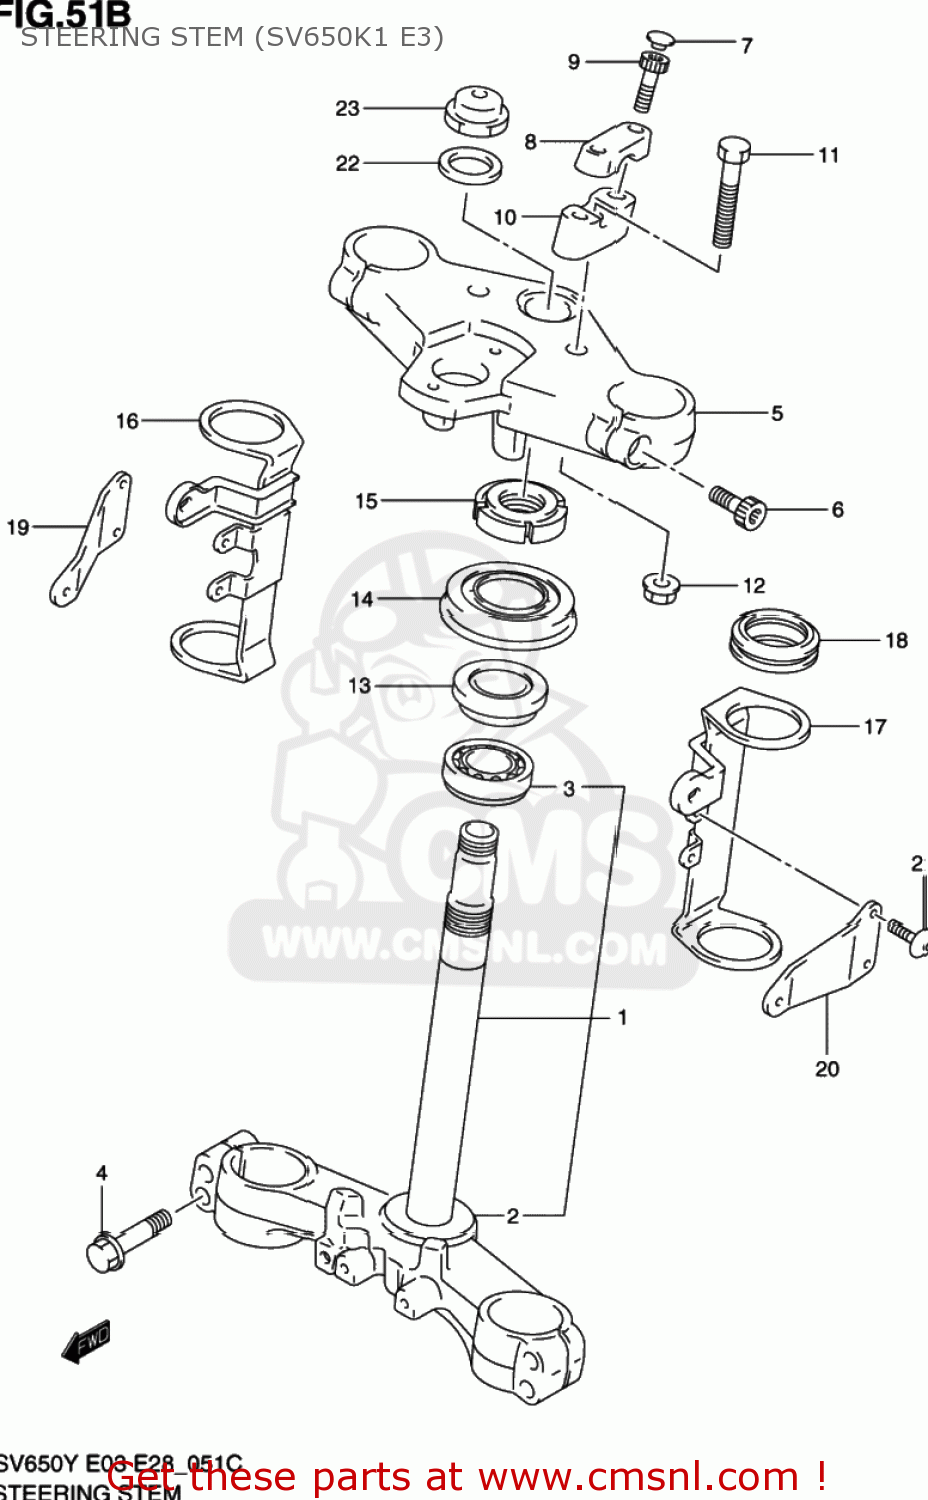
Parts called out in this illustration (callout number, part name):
1	STEM,STEERING
2	SEAL,STEERING LWR
3	BEARING(30X55X17)
4	BOLT
5	HEAD,STEERING STEM
6	BOLT(8X32)
7	CAP(OD:11)
8	HOLDER,HANDLE
9	BOLT
10	HOLDER,HANDLE LWR
11	BOLT,LWR HOLDER(10X45)
12	NUT
13	BEARING(25X47X15)
14	SEAL,OIL(34X69X11.9)
15	NUT,STEERING STEM
16	BRACKET,HEADLAMP HOUSING,R
17	BRACKET,HEADLAMP HOUSING,L
18	DAMPER,HEADLAMP HSG BRACKET
19	STAY,HEADLAMP HOUSING,R
20	STAY,HEADLAMP HOUSING,L
21	SCREW(6X12)
22	WASHER(22.5X35.9X1.6)
23	NUT
